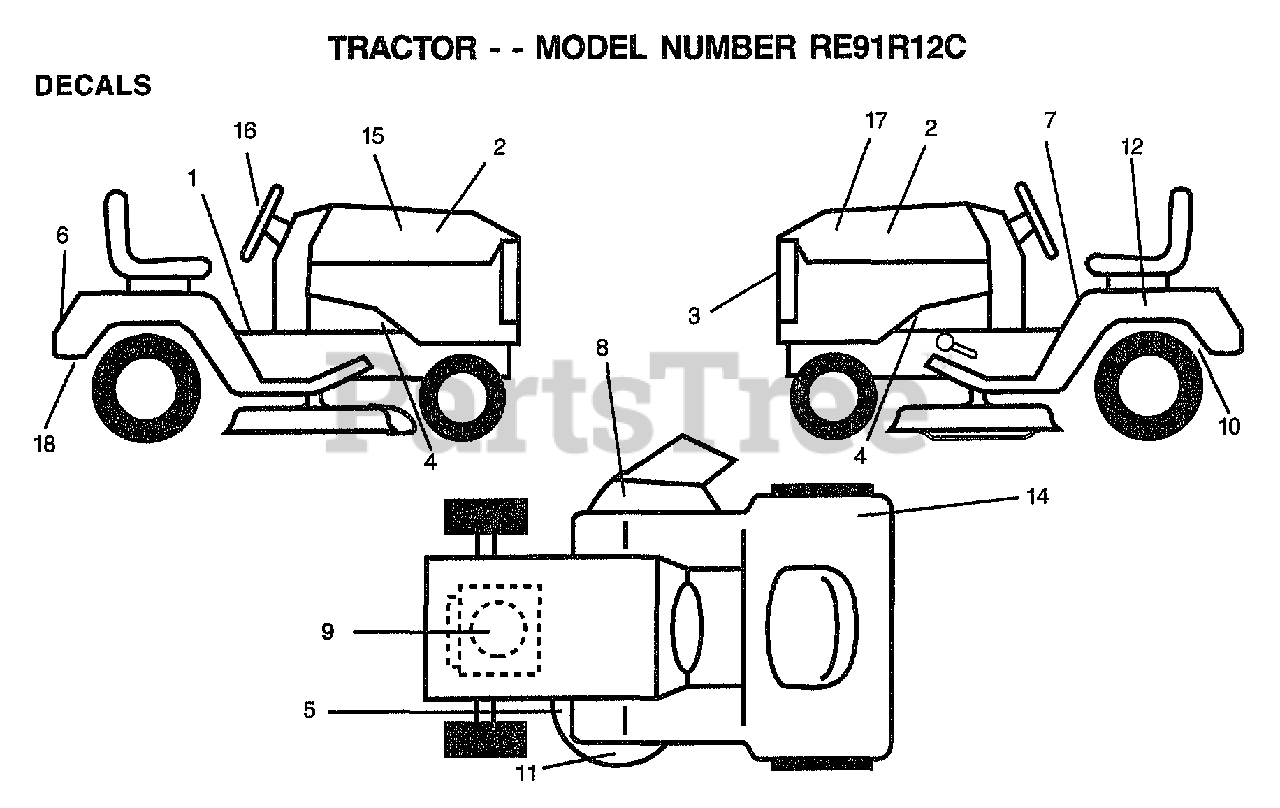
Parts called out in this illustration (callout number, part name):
1	DECAL CLUTCH/BRAK
2	"DECAL INSERT,HOOD"
3	GRILL DECAL
4	"DECAL CHASSIS,HOT"
5	DECAL.V.BELT
6	FENDER DECAL
7	DECAL.READ.O.MANU
8	DECAL.DANGER.CUTF
10	DECAL.DRAWBAR.LDL
12	DECAL.BATRY.3-3908
15	DECAL HD RLY RH
16	"DECAL,STR WHL"
17	DECAL HD RLY LH
18	DECAL.EURO.ST.CE.
